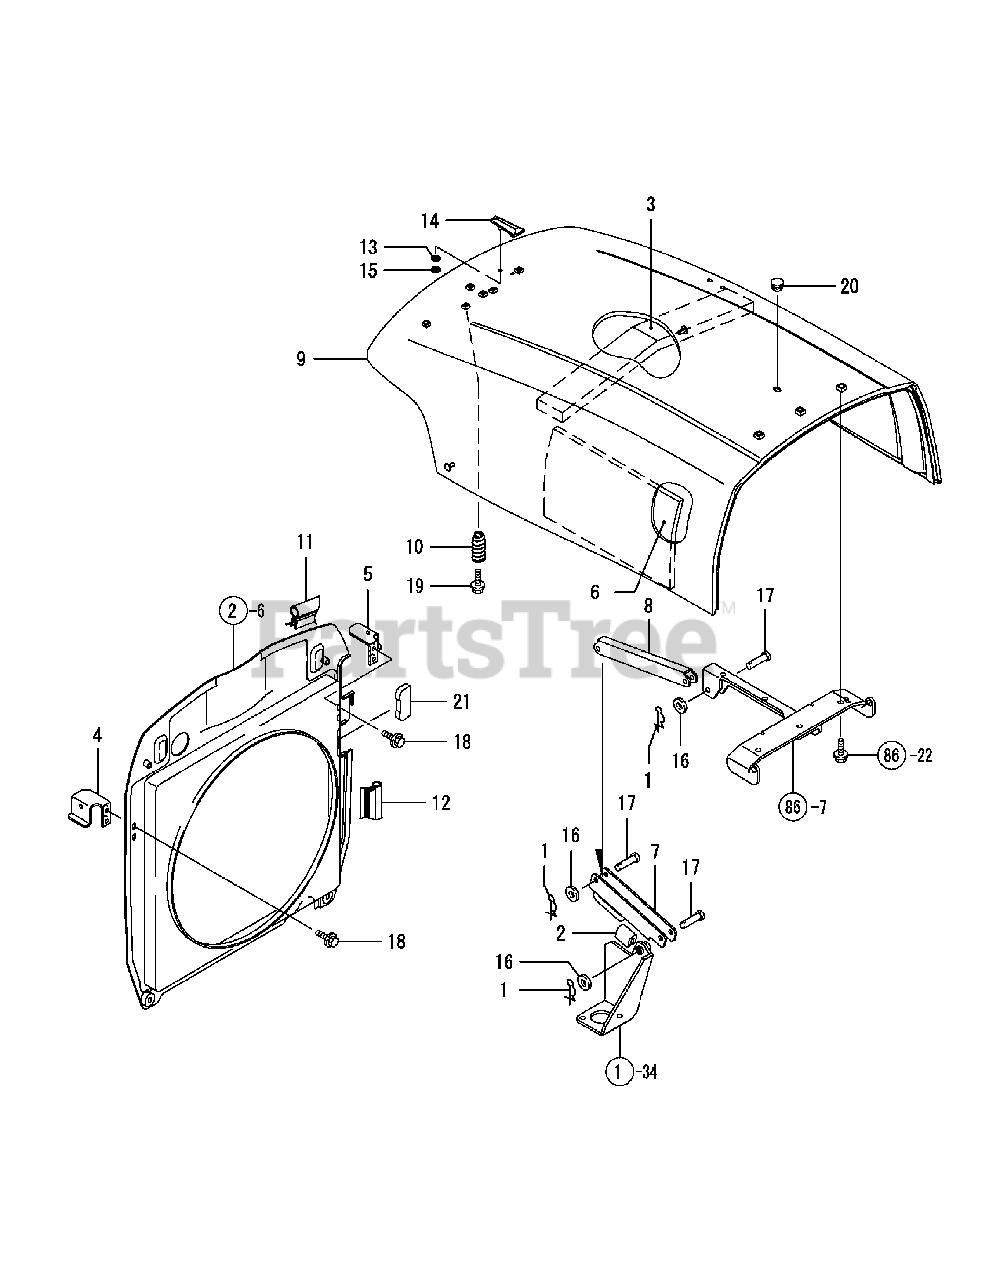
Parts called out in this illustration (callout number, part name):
1	PIN 8,COME-OFF SNAP
3	URETHANE, HOOD UPPER
6	URETHANE, HOOD UPPER
11	WEATHER-STRIP, A
12	WEATHER-STRIP, B
15	NUT M5,SPEED
16	WASHER 8, POLISHED
18	BOLT M 6X 12 PLATED
19	BOLT M 6X 16 PLATED
21	GROMMET SHROUD
